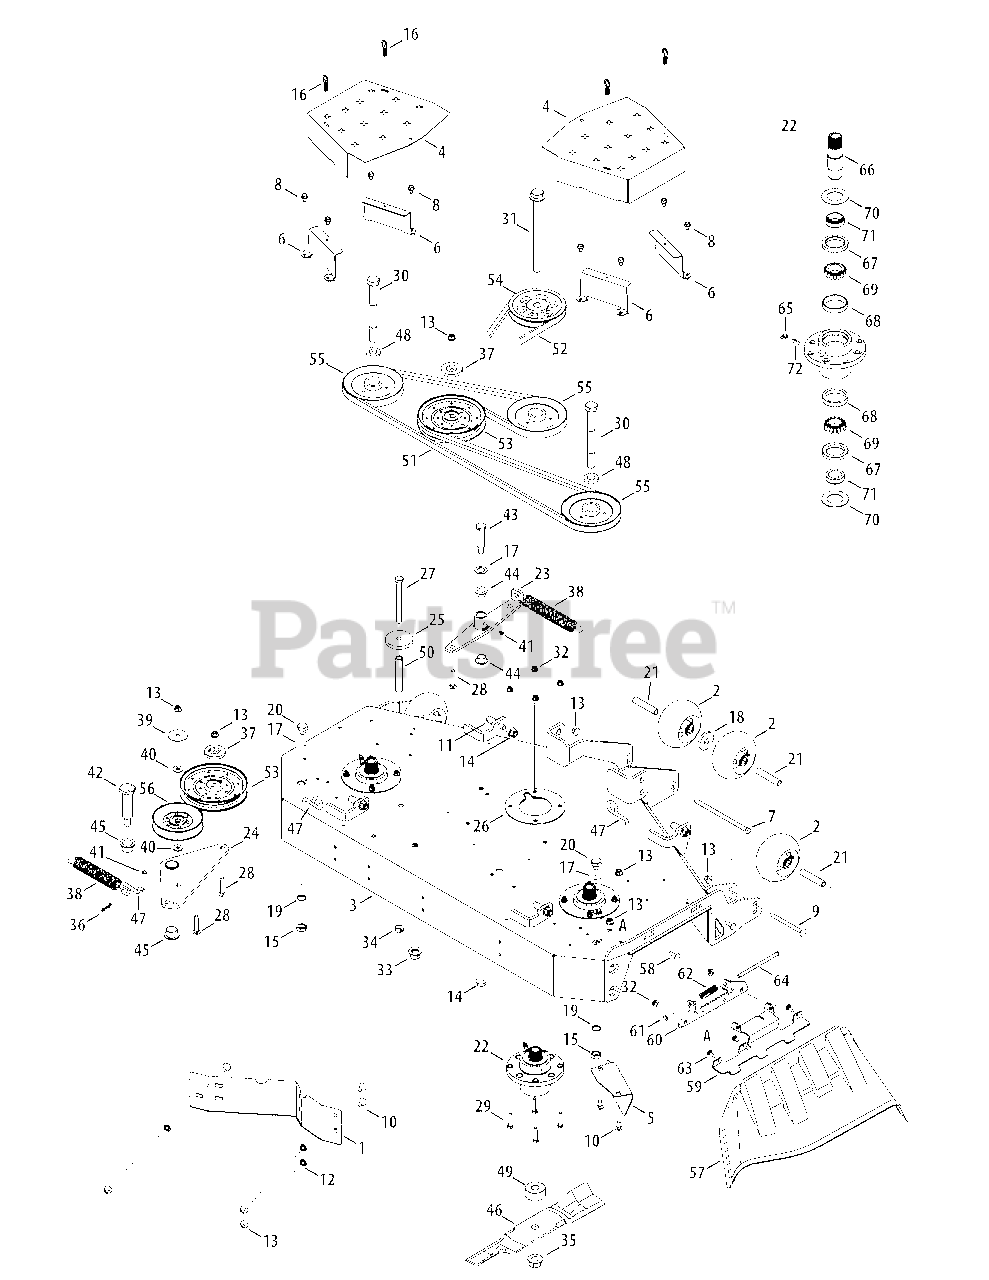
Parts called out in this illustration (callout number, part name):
1	Baffle, 54" Adjustment
2	Complete Wheel, 5.00 Dia.
3	54" Deck FAB
4	Deck Belt Cover
5	Chute Baffle
6	Beck Belt Cover Bracket
7	Hex Cap Screw, 3/8-16 x 7.25
8	Screw, 5/16-18 x .500
9	Carriage Screw, 3/8-16 x 4.50
10	Carriage Bolt, 3/8-16 x .750
11	Pin, 1/2-13 x .625 x 1.2
12	Push Nut, 3/8
13	Nut, 3/8-16, Flangelock
14	Nut, 1/2-13, Flangelock
15	Hex Nut, M16-1.5
16	Folding Latch Panel
17	Washer, .793 x 1.24 x .06
18	Flat Washer, .632 x 1.00 x .160
19	Lock Washer, 17 x 23.8 x 1.95
20	Plug, Screw, M16-1.5
21	Wheel Spacer
22	Spindle Assembly
23	Deck Idler Arm
24	Idler Assembly
25	Spacer, .5375 x 2.75 x .375
26	Spindle Support Plate
27	Hex Cap Screw, 1/2-13 x 5.00
28	Screw, 3/8-16 x 2.00
29	Bolt, 5/16-18 x 1.25
30	Hex Cap Screw, 3/4-16 x 7.00
31	Hex Cap Screw, 3/4-16 x 9.00
32	Nut, 5/16-18, Flangelock
33	Nut, 5/8-18, Flangelock
34	Nut, 1/2-13, Hexlock
35	Nut, 3/4-16, Flangelock
36	Bow Tie Cotter Pin
37	Pulley Cap
38	Extension Spring, 1.248 x 8.5
39	Washer, .406 x 1.92 x .060
40	Washer, .406 x 1.00 x .105
41	Grease Fitting
42	Shoulder Bolt, 1.0 x 3.15, 5/8-18
43	Shoulder Bolt, .750 x 2.23, 1/2-13
44	Flange Bearing, .75 x .52
45	Flange Bearing, 1.00 x .75
46	Hi-Lift Blade, 19.0
47	Spring Rod Hook
48	Spacer, .812 x .218
49	Spacer, .760 x 2.00 x .925
50	Spacer, .405 x .75 x 3.875
53	Idler Pulley
54	Pulley, 6.96 OD x .750 ID
55	Spindle Pulley
56	Idler Pulley
57	Discharge Chute Assembly
58	Carriage Bolt, 5/16-18 x 1.00
59	Chute Bracket
61	Push Cap
62	Torsion Spring
63	Shoulder Screw, 1/4-20
64	Chute Rod
65	Grease Fitting, 45 degree, 1/4-28
66	Spindle Shaft
67	Seal, Oil
68	Cup Bearing
69	Cone Bearing
70	Washer, 1.50 x 2.52 x .075
71	Ring, Seal
72	Straight Adapter Fitting
